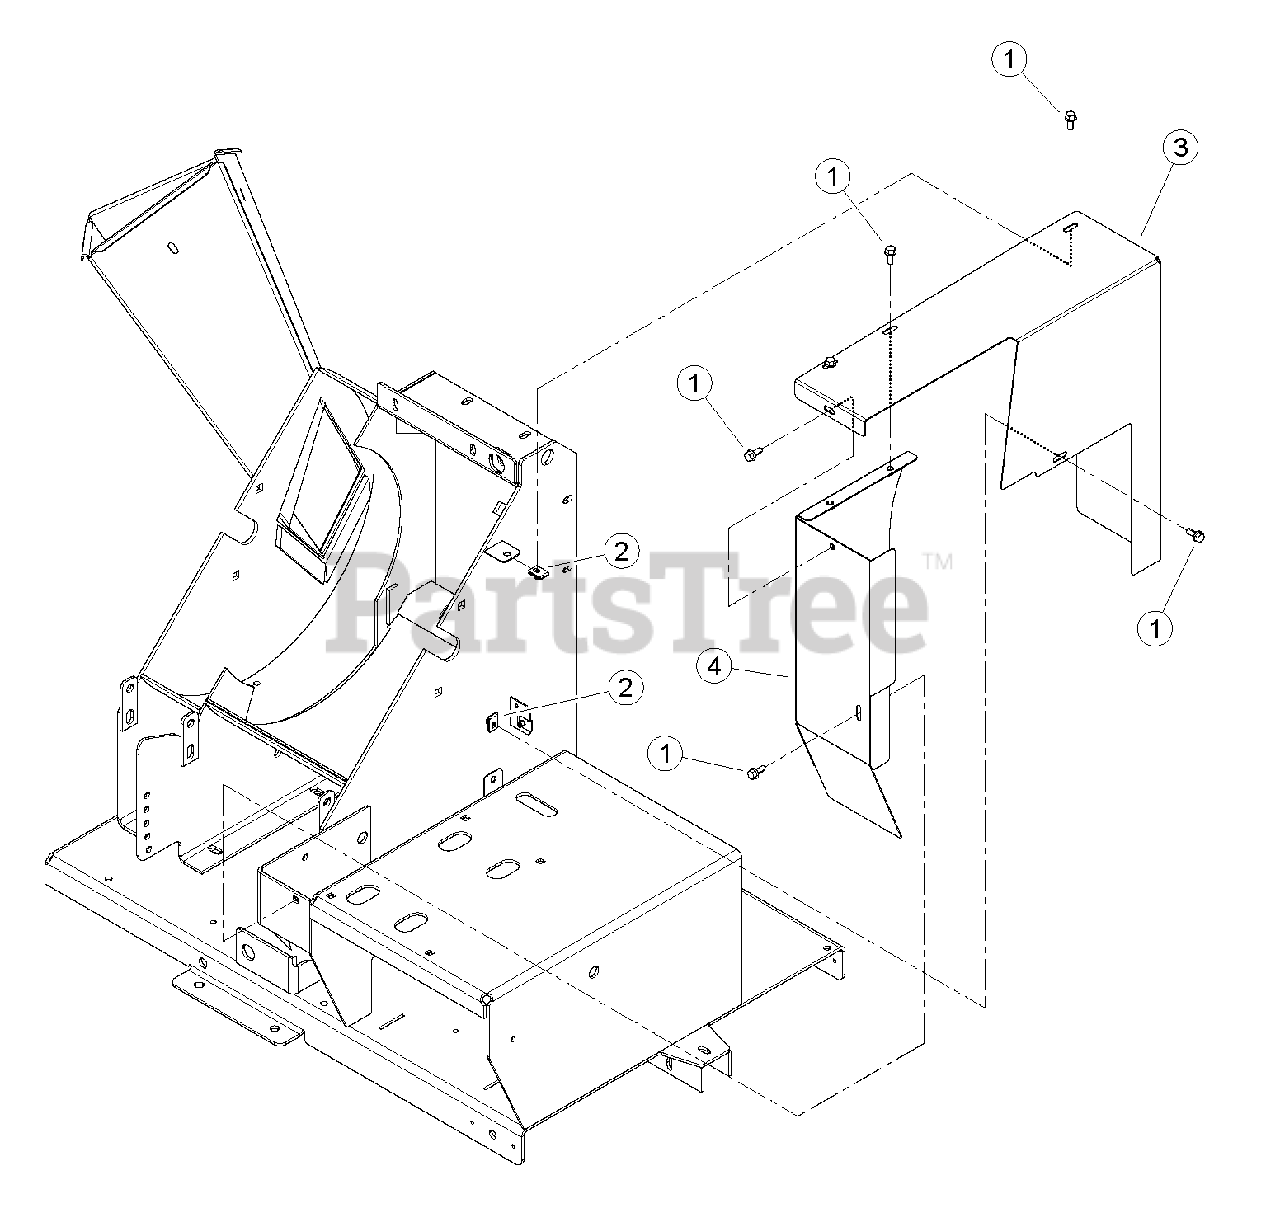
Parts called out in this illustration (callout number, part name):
1	BOLT, 5/16 X 3/4 FLANGE NC
2	NUT, 5/16"-18 TINNERMAN U-TYPE
3	SHIELD, BELT
4	WELDMENT, SHIELD
